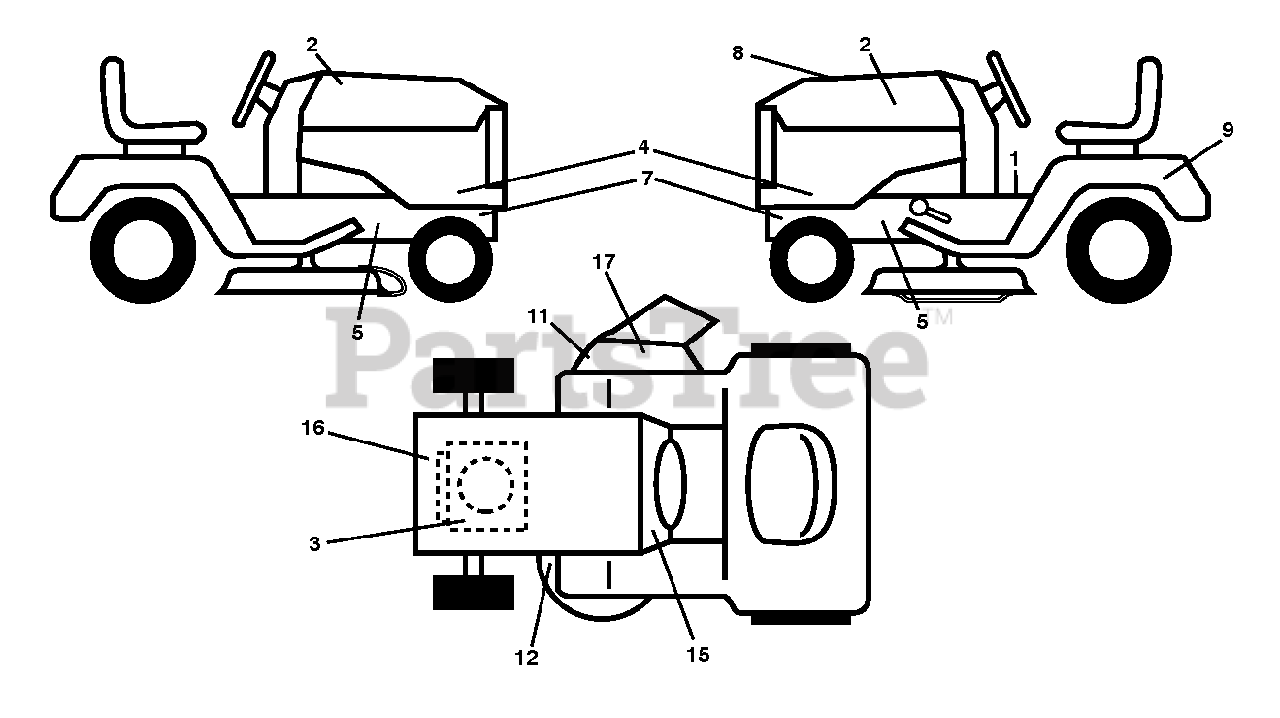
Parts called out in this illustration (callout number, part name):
1	DECAL TRACTOR SADDLE DECAL DEC
2	DECAL.BADGE.170MM.TEXTLOGO.
3	DECAL.ENGINE.WARNING
4	DECAL.SDPNL.HUSQLT.TS142.HUSQV
5	DECAL.CHASSIS.HOT.MUFFLER
7	DECAL.WARNING.SERVCE/FIRE
8	DECAL DECAL.RPL.BSM31.INTK.TLW
9	DECAL BTRY SYMBOLS
11	DECAL.DFLCTR.WARNNG.CTFNGR.SYM
12	DECAL.V-BELT.SCH.42/46"MEC/ELE
15	DECAL.SNOWFLAKE.MS498.HUSQ
16	DECAL.ENG.B&S.HS.500CC.382338
17	DECAL, DECK DEFLECTOR, WARNING
